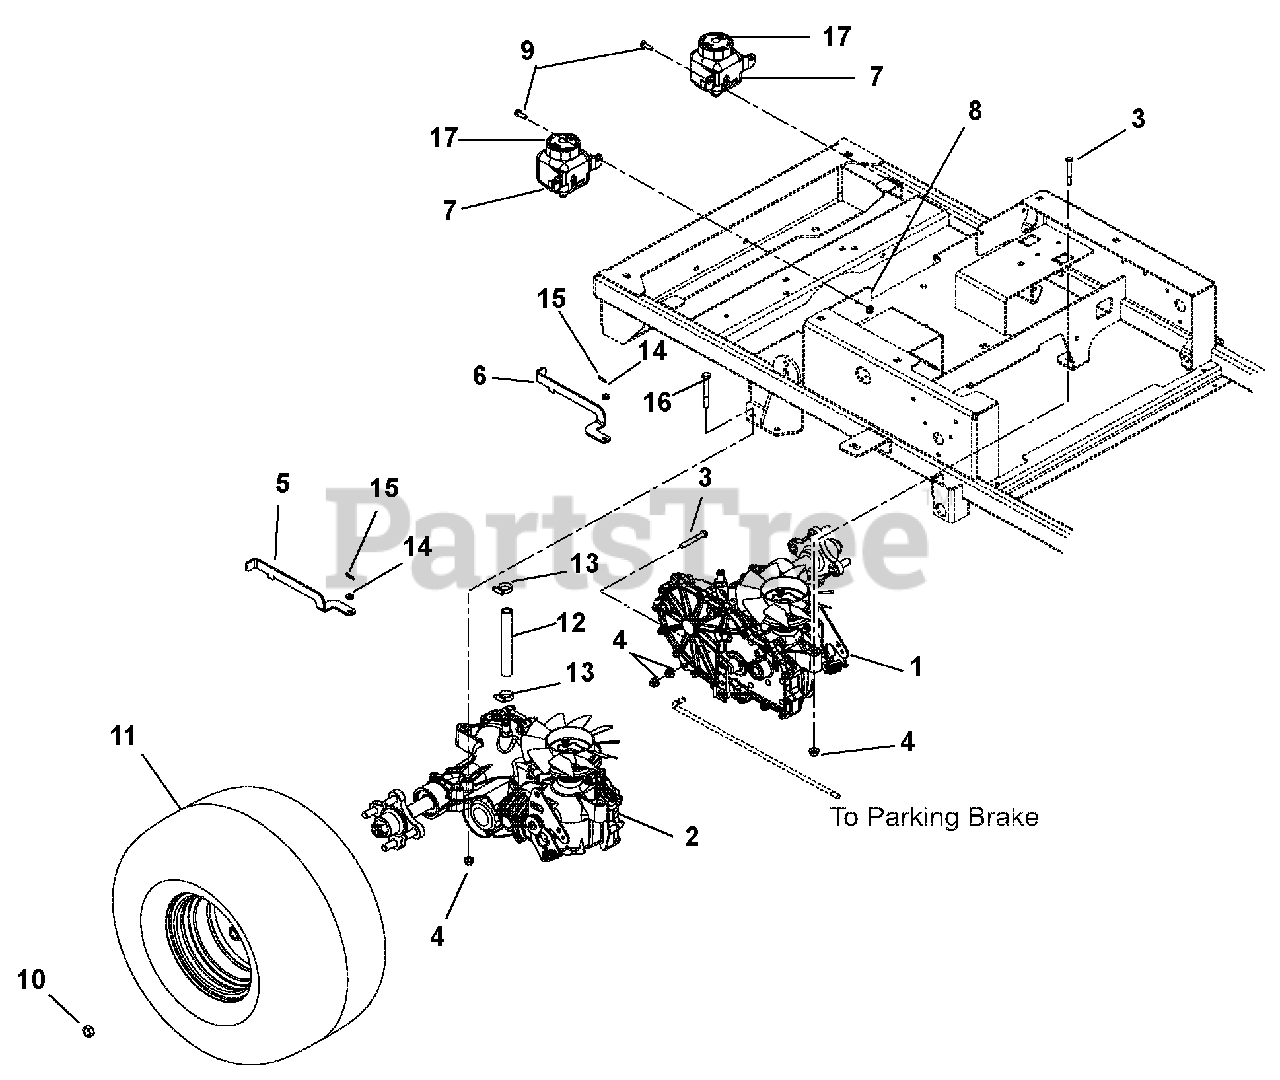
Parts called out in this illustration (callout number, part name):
1	TRANSAXLE, ZT2800 LH
2	TRANSAXLE, ZT2800 RH
3	@BLT-HEX .31-18X2.25 GR5 YWZC
4	@NUT-LK-NYL-FLG .31-18 YWZC
5	DUMP VALVE, RH
6	DUMP VALVE, LH
7	TANK, EXPANSION
8	@NUT-LK-TOP-FLG .25-20 YWZC
9	@BLT-HEX .25-20X.75 GR5 YWZC
10	WHEEL NUT .500-20 YZ
11	TIRE/WHEEL ASSY, 20X10.0-8 CTR
11	TIRE/WHEEL ASM, 20X8.0-8 (SQ)
12	HOSE, OIL RESERVOIR
13	CLAMP,.88 DIA. HOSE
14	WSHR-FL-STL .265X.50X.087YWZC
15	PIN-HAIR INT .06X.18X.77
16	@BLT-HEX .31-18X2.75 GR5 YWZC
17	CAP, HYDRO RESERVOIR REPLAC.
